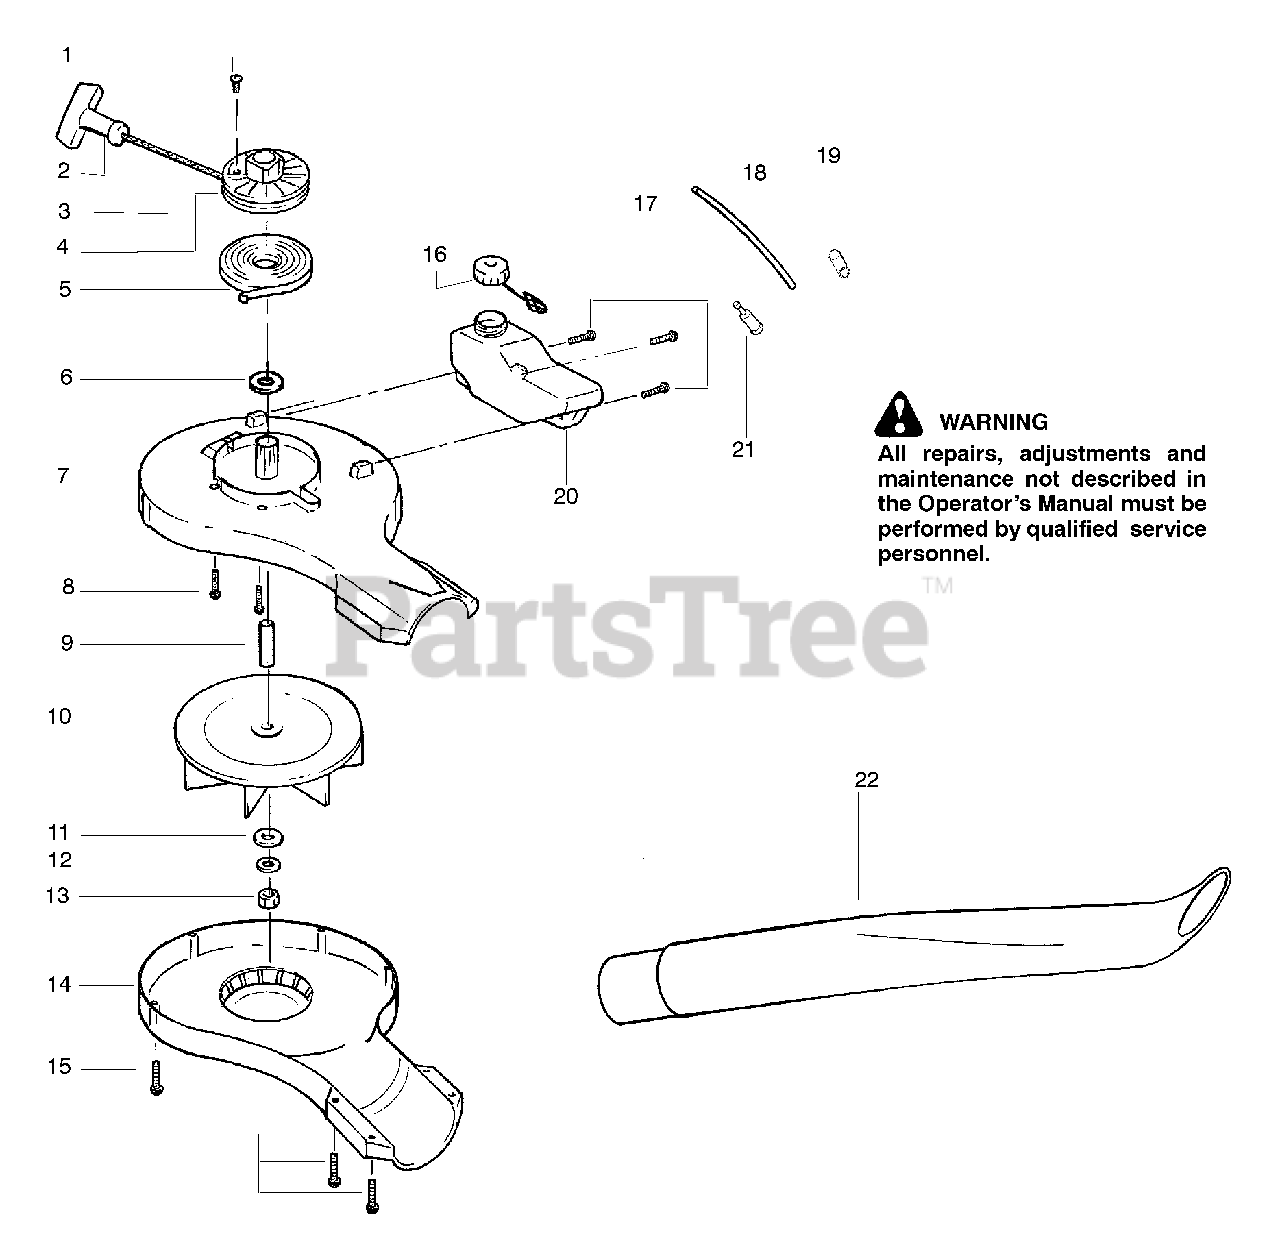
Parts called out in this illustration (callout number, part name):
2	Handle-Starter
3	Kit-Rope
4	Kit-Starter Pulley
5	Spring-Starter
7	Housing-Impeller (Upper)
9	Spacer-Flywheel
10	Assy-Impeller
11	Washer-Flat
12	Lockwasher
14	Assy-Impeller Housing (Lower)
16	Assy-Fuel Cap
18	Kit-Fuel Line
19	Grommet-Fuel Line
20	Assy-Fuel Tank
21	Fuel Pick-up Ass'y.
22	Tube-Blower
